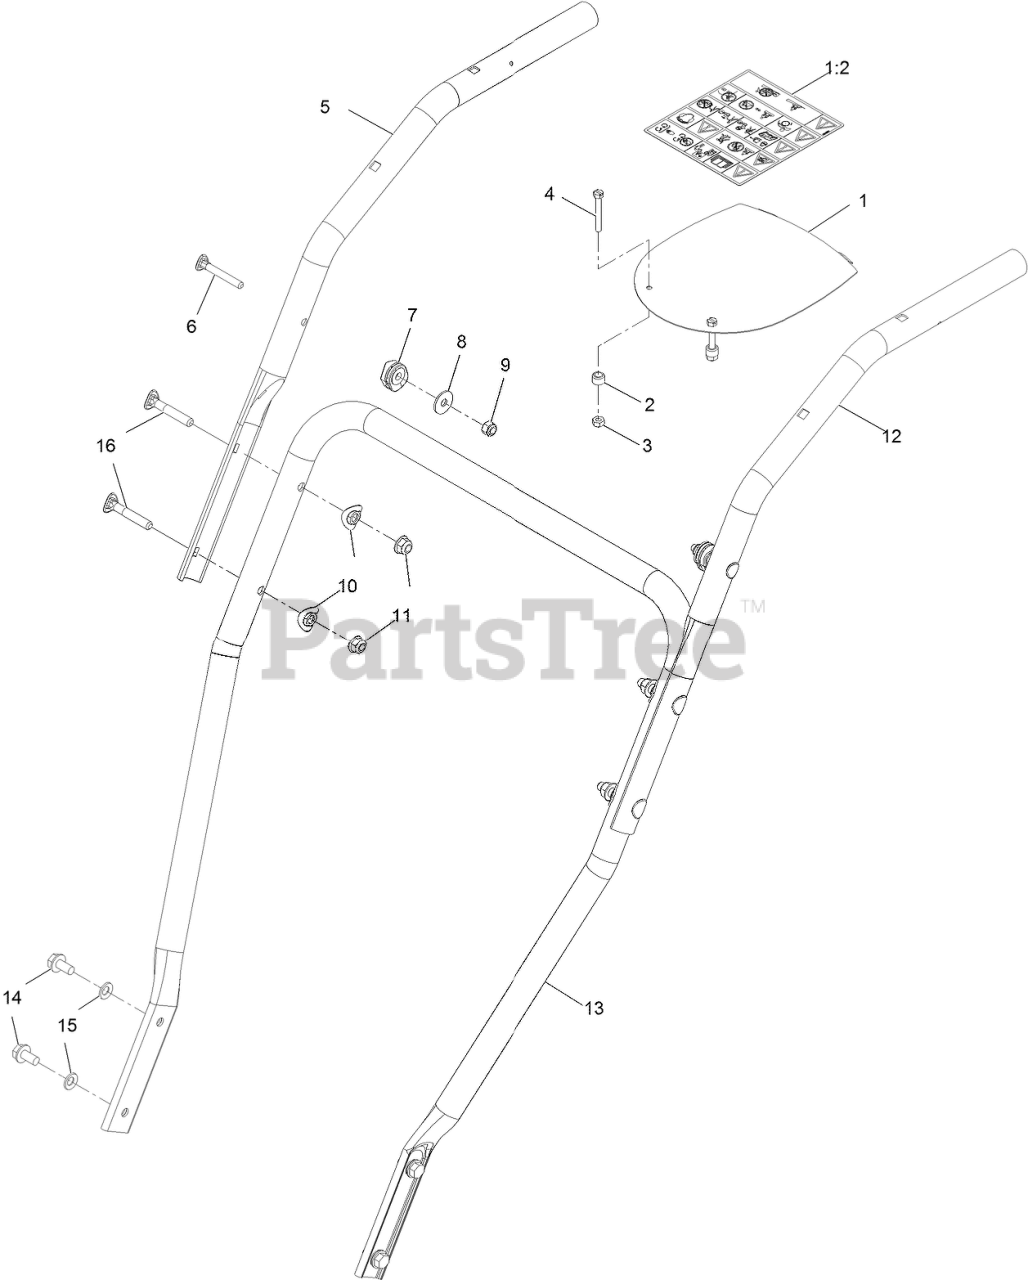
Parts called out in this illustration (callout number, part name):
1	PANEL-CONTROL
1:2	DECAL-CONSOLE
2	SPACER-BLADE, ROTOR
3	NUT-LOCK, NI
5	HANDLE-UPPER, RH
7	CLAMP-CABLE
8	WASHER-PLAIN
9	NUT-LOCK, NI
11	NUT-HF, NI
12	HANDLE-UPPER, LH
13	HANDLE-LOWER
14	SCREW-HWHTF
15	WASHER-BELLEVILLE
16	SCREW-HANDLE
